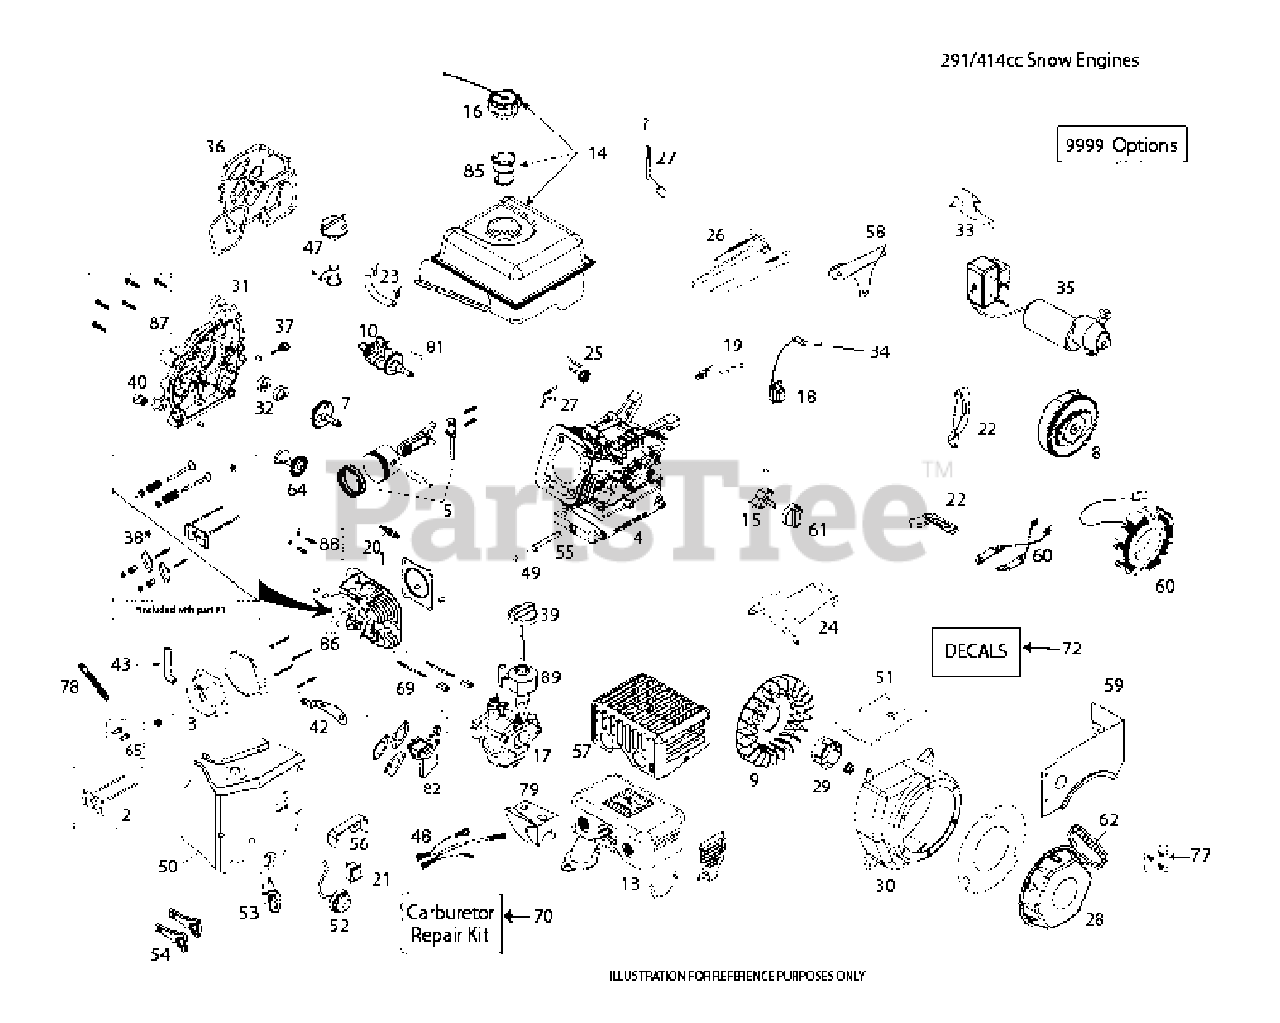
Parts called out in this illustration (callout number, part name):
1	CYLINDER.HEAD.ASSY(SK2911000)
2	PUSH ROD TAPPET KIT
3	VALVE.COVER.LCT.414CC.
4	CYLINDER ASSY SNO.LCT
5	PISTON.AND.ROD.ASSY(SK2911400)
6	CONNECTING ROD ASSY SNO.LCT
7	CAMSHAFT.LCT.291CC
8	FLYWHEEL.EL.ST.SKSNO2401.1
9	FLYWHEEL.FAN
10	Husqvarna TBD
13	MUFFLER (SKSN2210.1)
14	FUEL TANK ASSY - SNOW (291CC)
15	FUEL.PETCOCK.SNOW(SKSN4900)
16	FUEL.TANK.CAP.SNOW(SKSN4301)
18	COIL.IGN.CDI.SKSN2403.1
20	SPARK.PLUG(SK2911550)
21	ON/OFF.SWITCH.SNOW(SKSN4403)
22	SHIELD.U/FYWHL.CHARG(SKSN4604)
23	FUEL HOSE KIT
24	TOP.SHIELD.LCT.
25	GOVERNOR.GEAR.ASSY(SK2912900)
26	GOVERNOR.ARM.ASSY.(SKSN2502)
27	GOVERNOR.SHAFT.(SK2913100)
28	RECOIL.START.ASSY.(SKSN2600)
29	STARTER.CUP.SMALLSNOW(SKSN2601
30	BLOWER HOUSING.BLK ES LCT 291
31	CRANKCASE.COVER.ASY(SK2913600)
32	OIL.SEAL.KIT(SK2913900)
33	SWITCHBOX BRACKET ES LCT 291 S
34	SPARK.PLUG.BOOT.SNW,SKSN4691.1
35	STARTER, ELECTRIC, 230V
36	ENGINE.GASKET.KIT(SK2914300)
37	DIPSTK.OIL.BLK.LCTSK4143711.1
38	ROCKER ARM KIT
39	CHOKE.KNOW.SNOW(SKSN4500)
40	NONREMVABLE.OIL.PLUG(SK4143715
42	CDI.BOX.BRKT.SNOW(SKSN4402)
43	TUBE.BREATHER.LCT.219CC/414CC
47	TUBE OIL FILL KIT.LCT SKSN4950
48	WIRE.HARNESS(SKSN4406)
49	OIL.DRAIN.PLUG
50	HEATER.BOX.ASSY.SNOW(SKSN2100)
51	SHIELD.CYLINDER.SNOW(SK4141010
52	PRIMER.BULB.ASSY(SKSN4304)
53	KEY.SWITCH.ASSY.SNOW(SKSN4401)
54	KEY SET(2 KEYS) SKSN0407.1
55	OIL PIPE DRAIN EXTENDED.LCT SK
56	SHIELD.VAPOR(SKSN4606)
57	SHIELD.MUFFLER.
58	GOVERNOR.LINK.SHIELD(SKSN2501)
59	FUEL.TANK.SKIRT(SKSN2101)
60	ALTERN.60WATT.SKSN2402.1
61	FUEL KNOB-SNOW
62	HANDLE.RECOIL.DELUXE.LCT
65	TAPPET KIT.LCT.SK2911005.1
69	STUD.CARB.MOUTING.KIT.291CC
70	CARBURETTOR REPAIR KIT 291CC/4
77	BOLT.KIT.RECOIL.LCT.ALL.ENGINE
81	KEYS.FLYWHEEL.136/291CC.5PACK
82	SPACER.CARBURETOR.291CC.LCT
85	STRAINER.FUEL.TANK.LCT.208CC
86	KIT.BOLT.CYLINDER.HEAD.(4PC)
87	KIT.BOLT.CRANKCASE.COVER.291CC
88	STUD.MUFFLER.KIT.LCT
89	KNOB LCT.SKSN5325.1 SPEED
9999	HIGH.ALTITUDE.JET.(>6,000FT)
